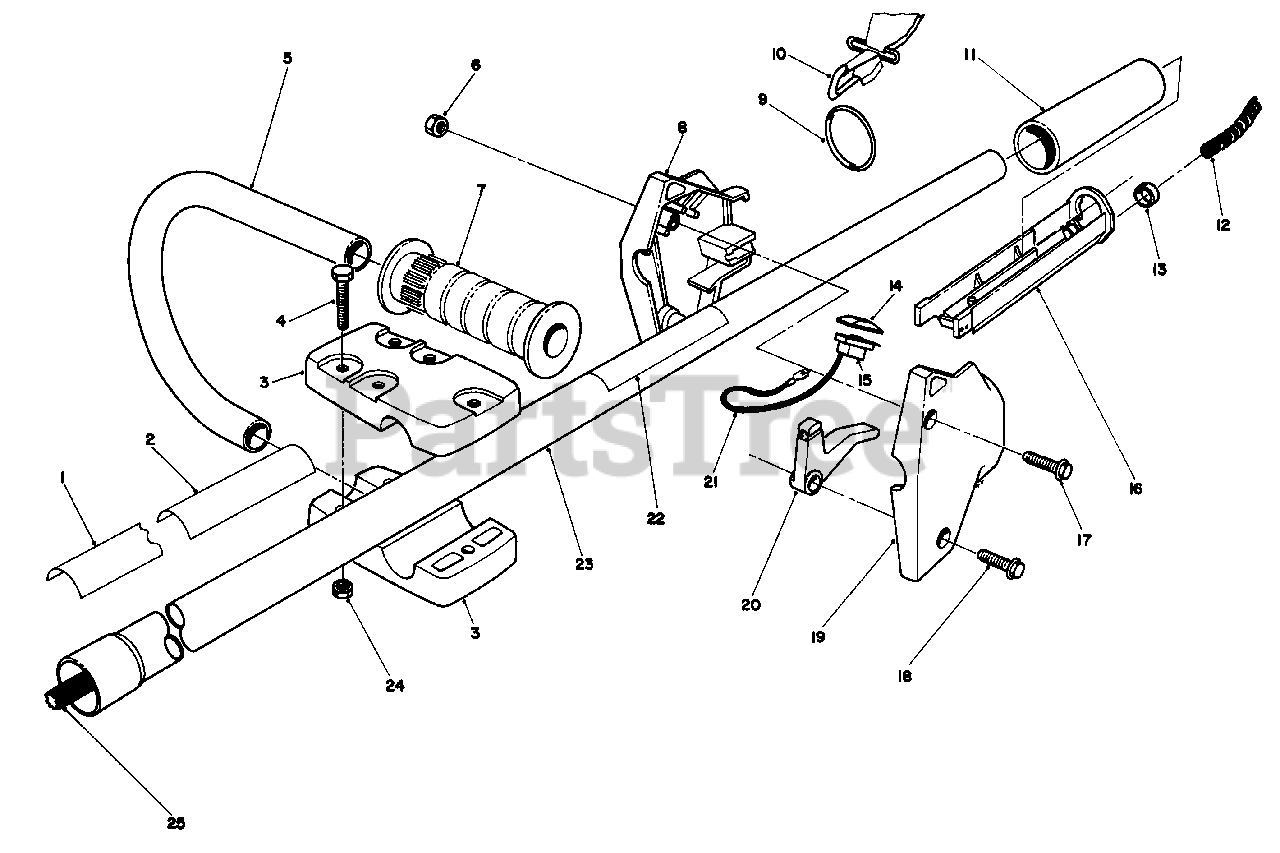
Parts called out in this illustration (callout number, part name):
1	Decal-TC 3500
2	Decal-Instruction
3	Clamp-Secondary
4	Hex Hd. Machine Screw
5	Handle-Secondary
7	Grip-Handle
8	Housing-R.H.
9	Ring-Harness
10	Harness-Shoulder
11	Grip-Drive Housing
12	Cover-Cable
14	Cap-Switch
17	Hex Washer Hd . Screw
18	Hex Washer Hd. Screw
19	Housing-L.H.
20	Lever-Throttle
21	Wire Assembly
22	Decal Danger
23	Tube Assembly
24	Locknut
25	Spline Shaft-Drive
